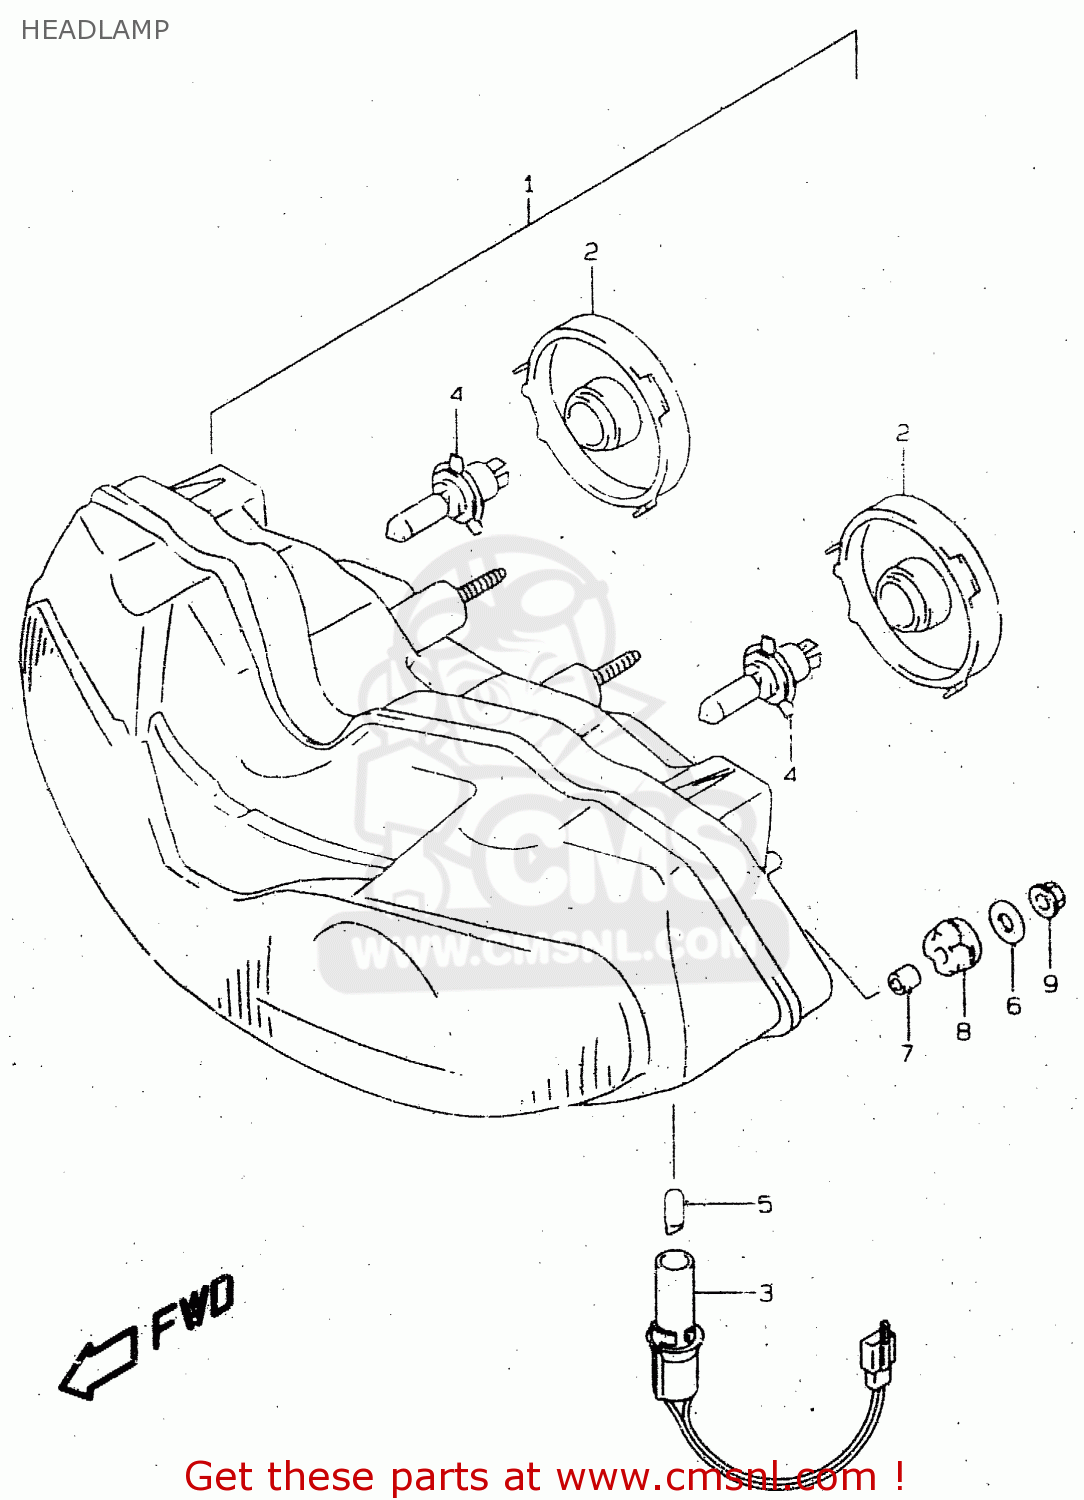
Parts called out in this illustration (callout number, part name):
1	HEADLAMP ASSY
2	COVER,SOCKET
3	SOCKET ASSY
4	BULB(12V60/55W,H4)
5	BULB(12V5W)
6	WASHER(6.5X20X1.6)
7	SPACER(6.5X9X13.5)
8	CUSHION
9	NUT
